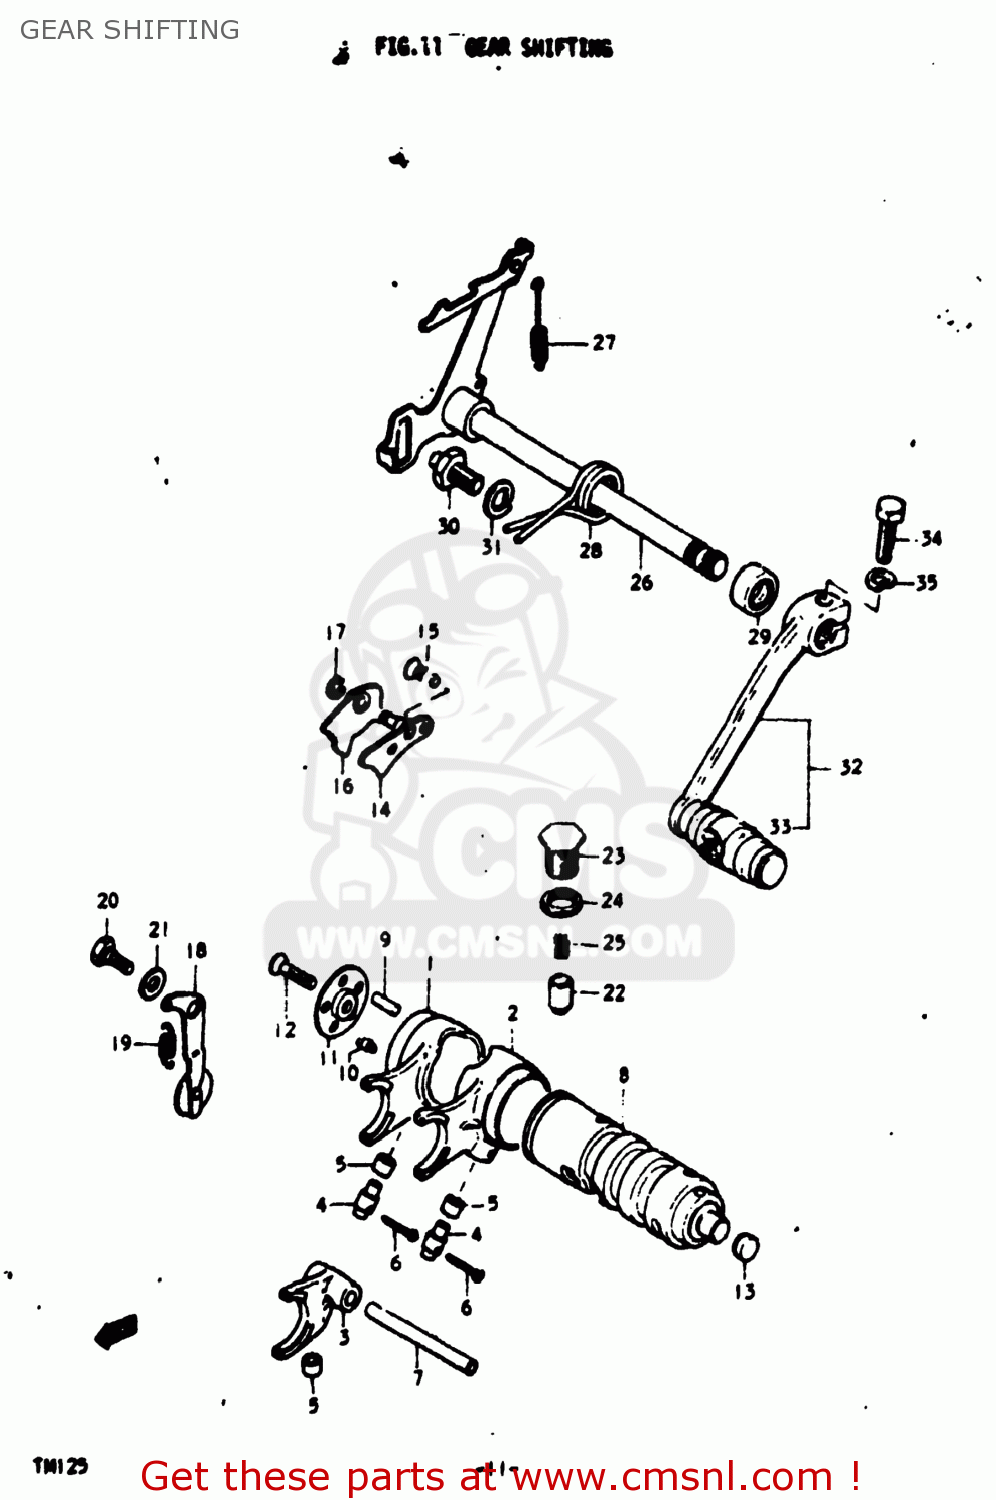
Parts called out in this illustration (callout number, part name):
1	FORK,GEAR SHIFT NO.1
2	FORK,GEAR SHIFT NO.2
3	FORK,GEAR SHIFT NO.3
4	PIN
5	SPACER
6	PIN 25X20
7	SHAFT,GEAR SHIFT FORK
8	CAM,GEAR SHIFT
9	ROLLER(4X13.8)
10	PIN
11	RETAINER,GEAR SHIFT CAM DR PIN
12	SCREW
13	PLUG
14	GUIDE,GEAR SHIFT CAM
15	SCREW
16	PAWL,GEAR SHIFTING CAM
17	E RING
18	STOPPER,SHIFT CAM
19	SPRING
20	BOLT(6X16.1)
21	WASHER(6.5X16X2.3)
22	STOPPER,GEAR SHIFTING
23	HOLDER,SHIFTING CAM STOPPER
24	GASKET(14X19.2X2) (NAS)
25	SPRING
26	SHAFT,GEAR SHIFT
27	SPRING
28	SPRING
29	OIL SEAL
30	STOPPER,GEAR SHIFT ARM
31	LOCK WASHER
32	LEVER ASSEMBLY,GEAR SHIFTING
33	RUBBER,GEAR SHIFT PEDAL
34	BOLT
35	LOCK WASHER
